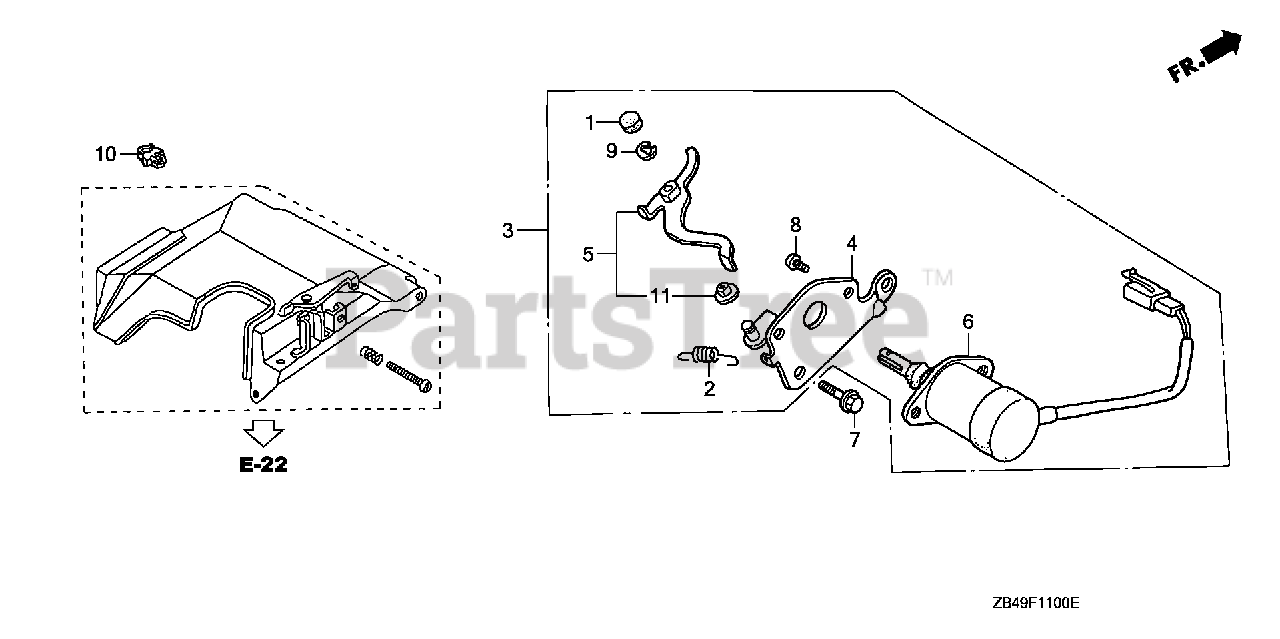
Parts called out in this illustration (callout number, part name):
1	CAP, CHOKE LEVER
2	SPRING, CHOKE RETURN
3	AUTO-THROTTLE ASSY.
4	STAY, SOLENOID THROTTLE
5	LEVER, SOLENOID THROTTLE
6	SOLENOID ASSY.
7	BOLT, FLANGE (6X12) (CT200)
8	SCREW, PAN (5X8)
9	E-RING (4MM)
10	CLIP, TUBE
11	BUSH, AUTO-THROTTLE LEVER
